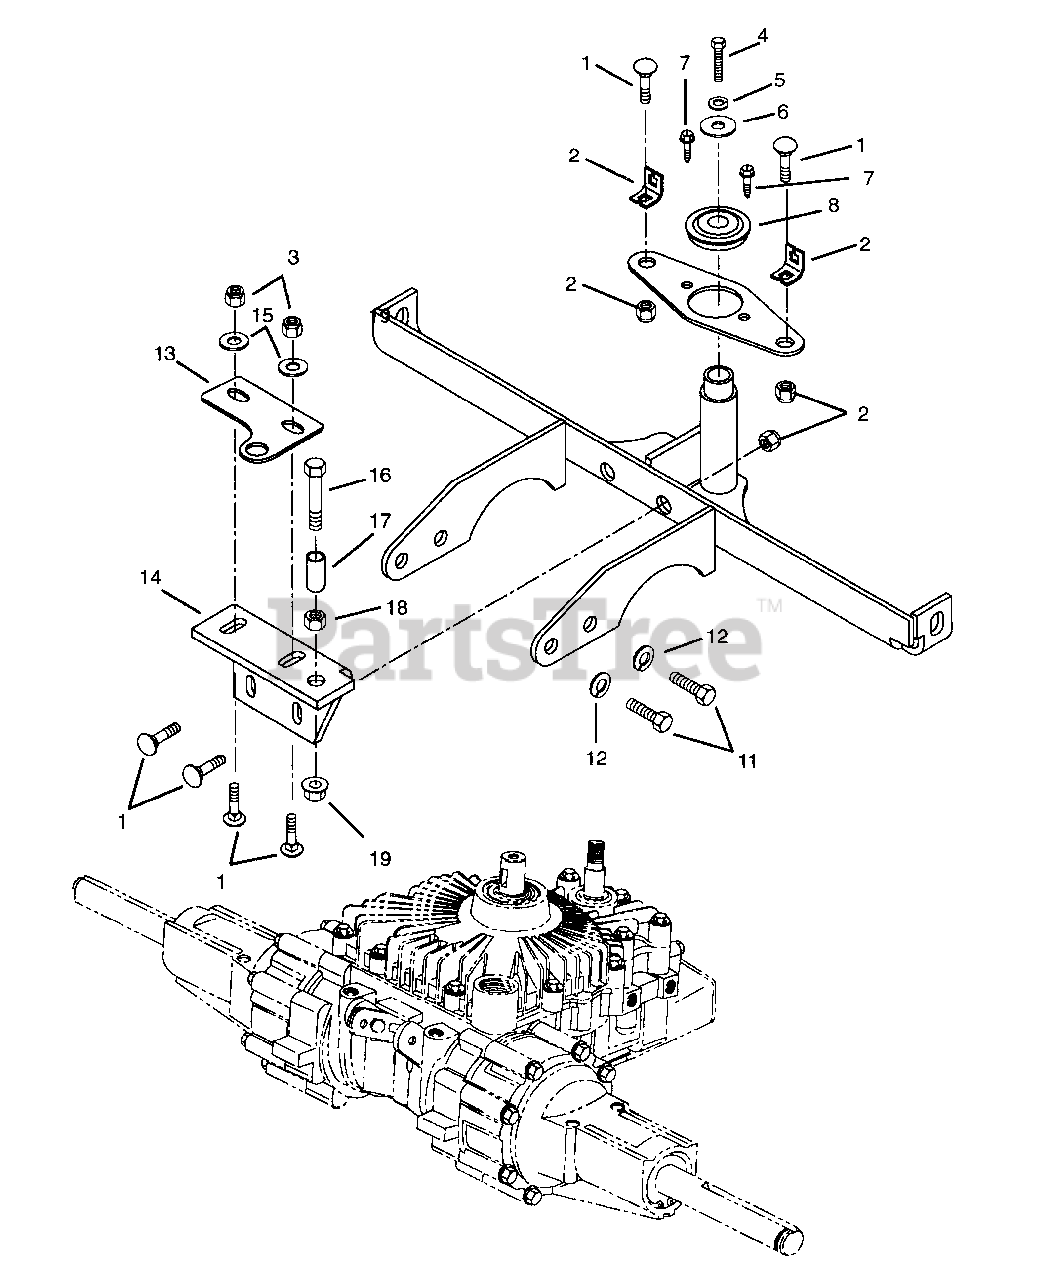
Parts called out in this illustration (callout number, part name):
1	Bolt-Round Head Square Neck .31-18 x .75
2	Bracket, Lower Cable
3	Nut-Locking-Nylon .312-18
4	Screw-Tapping .312-18 x .50
5	Washer-Lock .312 x .097
6	Washer-Flat-Steel .38 x .875 x .083
7	Screw-Tapping .250-20 x .37
8	Bearing-Ball .625 x 1.382 x .50
9	Lever, Cable Swing
10	Weldment, Transmission Torque Mount
11	Bolt-Hex .31-18 x .75 Grade 5
12	Washer-Lock .313 x .078
13	Plate, Neutral Switch
14	Bracket, Neutral Switch
15	Washer-Flat-Steel .344 x .688 x .065
16	Bolt-Hex .38-16 x 2.50 Grade 5
17	Spacer, Steering Cable
18	Nut-Hex .375-16 Grade 2
19	Nut-Locking-Nylon .375-16 Grade 2
